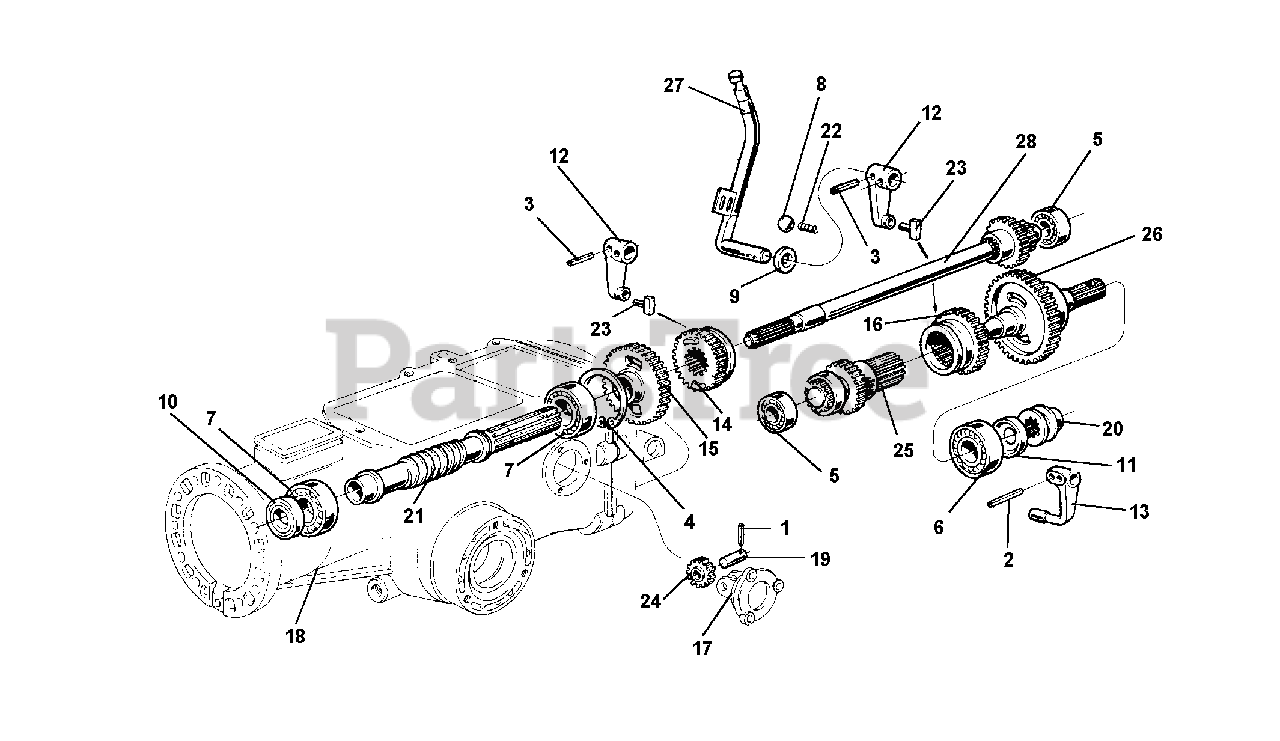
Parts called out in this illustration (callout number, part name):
1	PIN, LOCKING 2.5 X 22 DIN 1481
2	LOCKING PIN 4 X 20 SPIRAL
3	LOCKING PIN 4 X 24 SPIRAL
4	CIRCLIP, INTERN D 52
5	BEARING 15 X 35 X 11 6202
6	BEARING 20 X 47 X 14 6204
7	BEARING 25 X 52 X 15 6205
8	BALL 15/32 RIV RB-11.906
9	SEAL, OIL 12 X 19 X 5 STANDARD
10	SEAL, OIL 15 X 40 X 10 STANDARD
11	SEAL, OIL 20 X 35 X 7 STANDARD
12	LEVER, SPEED CHG SLDG GR
13	SLIDE ELVER
14	SLIDER SPEEDS
15	WHEELS FIRST SPEED
16	SLIDER, REDUCTION UNIT
17	FLANGE, REVERSE SPEED
18	CASING 5 SPEEDS GEARBOX
24	REVERSE SPEED GEAR
25	GEAR TRIPLE
26	P.T.O. SHAFT
27	SHIFT LEVER
28	CLUTCH SHAFT
